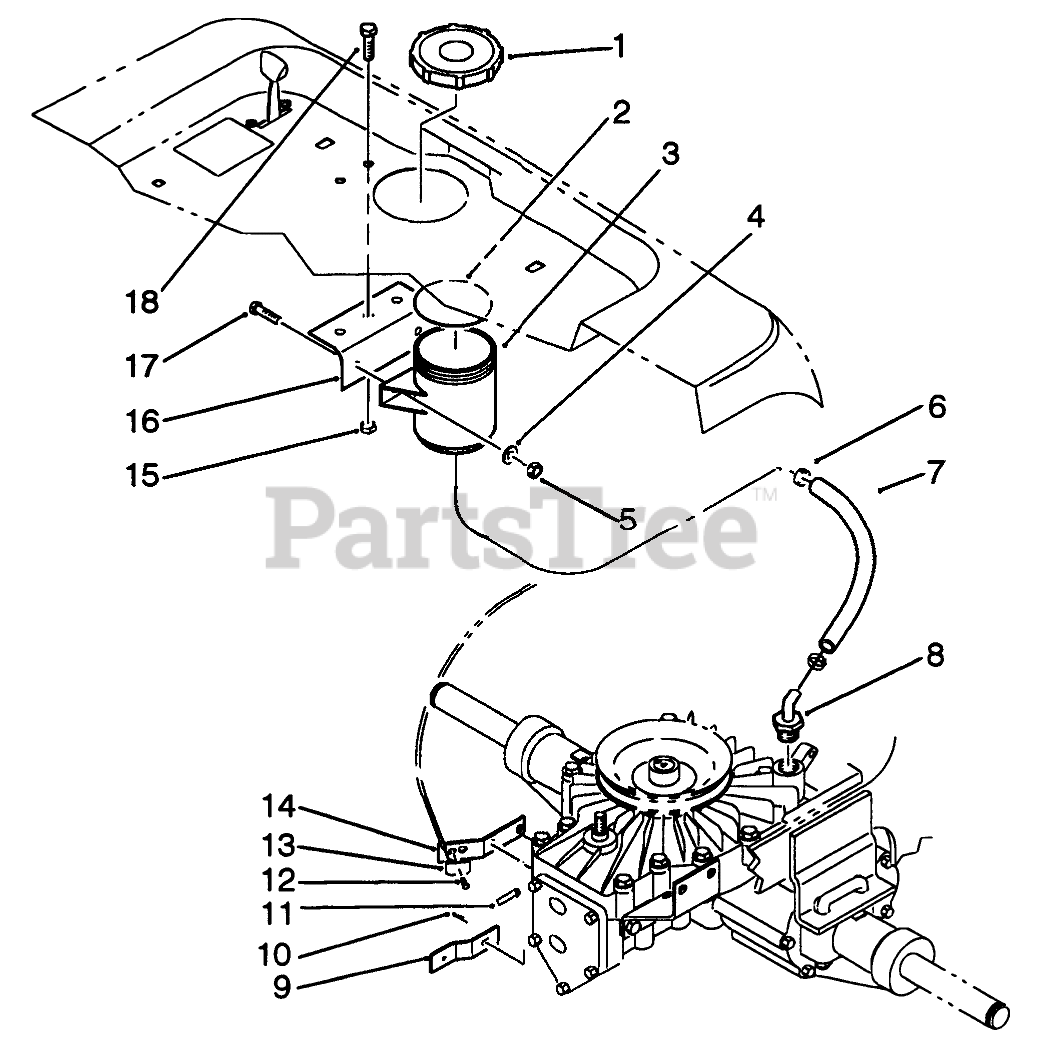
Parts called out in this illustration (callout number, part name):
1	ASS'Y-RESERVOIR
2	COVER GASKET
3	RESERVOIR
4	WASHER-FLAT
5	NUT-LOCK, NI
6	CLAMP .875
7	HOSE-7"
8	HOSE BARB
9	Plate
10	Cotter Pin
12	Screw
13	CLAMP THROTTLE
14	PLATE-MTG
15	NUT-LOCK, NI
16	BRACKET R
17	Bolt
18	SCREW-HH
